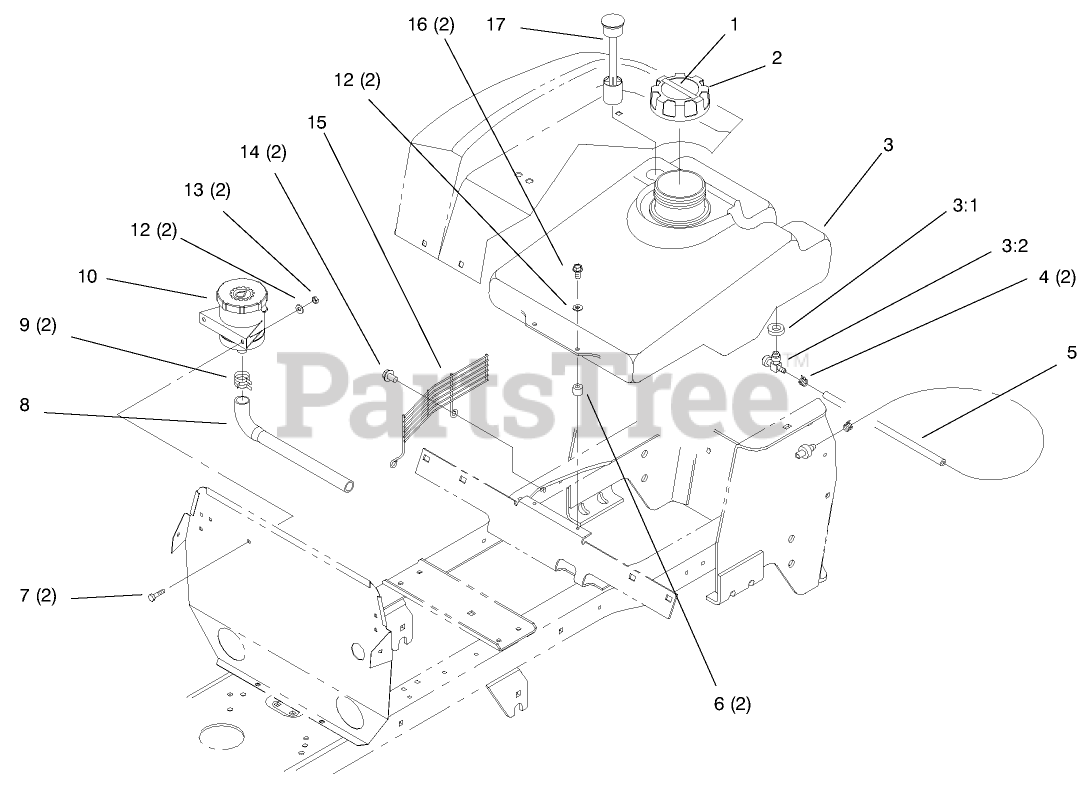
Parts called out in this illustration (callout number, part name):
2	GAS CAP ASM
3	TANK-GAS (FG50538)
3:2	VALVE-FUEL
4	CLAMP-HOSE
5	HOSE-FUEL
6	SPACER - FUEL TANK
7	SCREW-HH
8	HOSE - HYDRO
9	CLAMP-HOSE
12	WASHER-FLAT
13	NUT-LOCK, NI
14	SCREW-HWHTF
16	SCREW-HH
